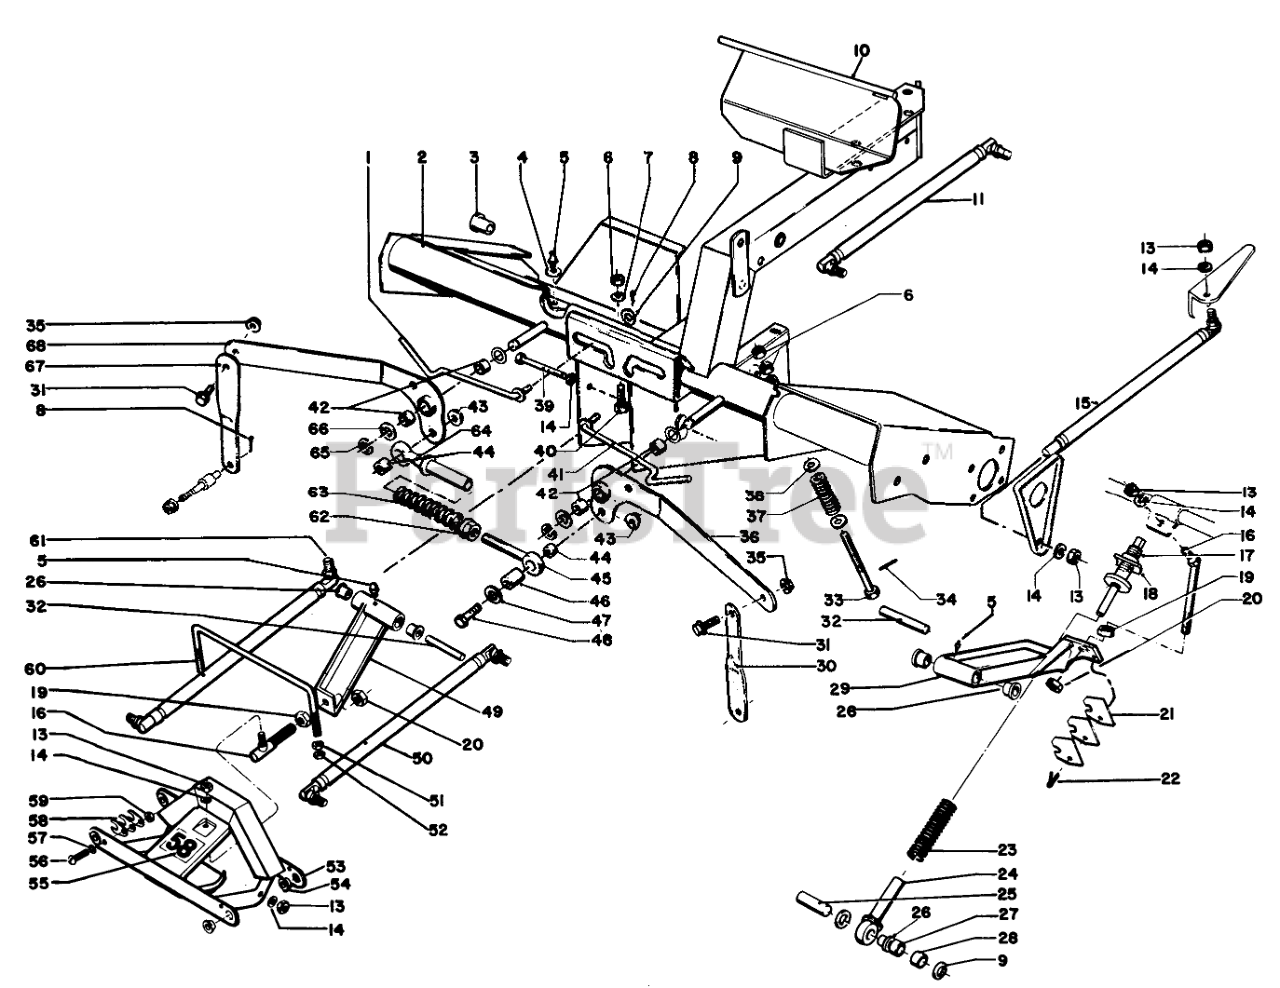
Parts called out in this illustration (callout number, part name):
1	Link-Transport R.H.
2	Main Frame (Incl. Ref. #3)
3	3/4IDX1LG FLANGE BSHG
4	WASHER-LOCK
5	FITTING-GREASE
6	NUT-HEX
7	WASHER-LOCK
8	PIN-COTTER
9	WASHER-FLAT
10	Mounting Plate
11	Ball Joint Assembly
13	NUT-HEX
14	WASHER-LOCK
15	Ball Joint Assembly
16	BALL JOINT
17	ANCHOR, SPRING COBAL
18	ADJUSTING NUT
19	NUT-LOCK, NI
20	NUT-JAM
22	PIN-COTTER
23	COMPRESSION SPRING
24	GUIDE & BUSHING WA
25	Spacer
26	BUSHING-FLANGE
27	SPLIT SPACER
28	Spacer
29	Mount-Counterbalance (Incl. Ref. #26)
30	Link-L.H.
31	SHOULDER BOLT
32	SPLIT SPACER
33	Screw
34	PIN-ROLL, SLOTTED
35	NUT-LOCK
36	Arm (Incl. Ref. #42)
37	SPRING
38	WASHER-PLAIN
39	SCREW-HH
40	SCREW-HH
41	Link-Transport L.H.
42	BUSHING
43	NUT-KEPS
44	BUSHING
45	Yoke (Incl. Ref. #44)
46	Spacer
47	WASHER-FLAT
48	SCREW-HH
49	Hitch-Yoke (Incl. Ref. #26)
50	BALL JOINT ASM
51	NUT-HEX
52	NUT-LOCK
53	Intermediate Frame (Incl. Ref. #54)
54	BUSHING-FLANGE
55	Decal
56	10-24 X 7/8 RND HD MS
57	SPACER
58	FRONT SIDE SHIM
59	NUT-LOCK, NI
60	Spring Stabilizer
61	BALL JOINT ASM
62	NUT-LOCK, FLANGE
63	Spring
64	Yoke (Incl. Ref. #44)
65	RING-RETAINING, EXTERNAL
66	WASHER-FLAT
67	Link R.H.
68	Arm (Incl. Ref. #42)
